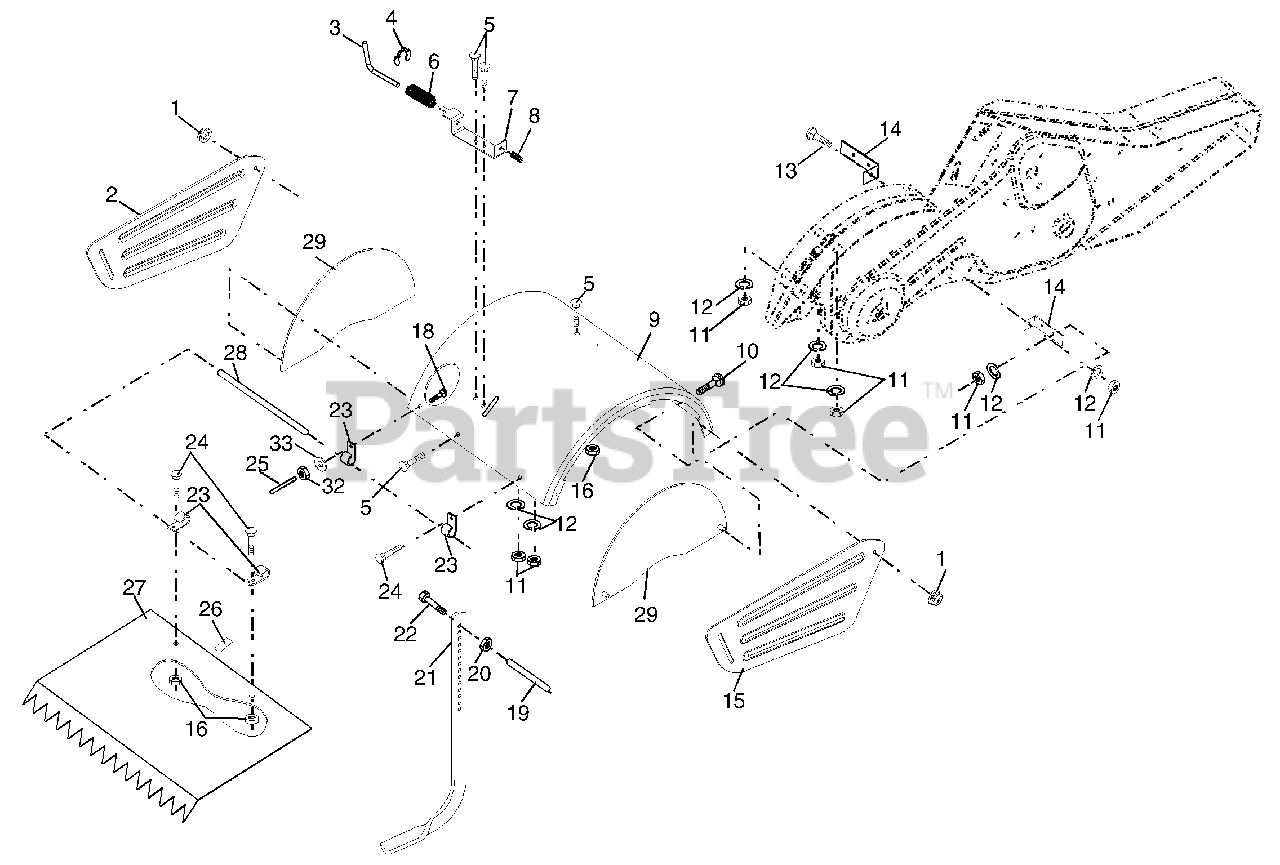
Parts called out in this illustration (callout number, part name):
1	Nut, Lock Hex Flange 5/16-18
2	Shield, Side, Outer L. H.
3	Pin, Stake, Depth
4	Ring, Klip
5	Bolt, Rdhd Sqnk 5/16-18 x 3/4
7	Bracket, Latch
8	Spring, Depth Stake
9	Shield, Tine
10	Bolt, Carriage 5/16-18 unc x 1
11	Nut, Hex 5/16-18
12	Washer, Lock 5/16
13	Bolt, Carriage 5/16-18 x 1-1/4
14	Bracket, Shield Tine
15	Shield, Side, Outer R.H.
16	Nut, Hex Flange 1/4-20 unc
18	Bolt, Carriage 1/4-20 x 1-1/4 Gr. 5
20	Nut, Hex 3/8-16
21	Stake, Depth
22	Bolt, Hex 3/8-16 x 2
24	Bolt, Carriage 1/4-20 x 1/2 Gr. 5
25	Cap, Vinyl
26	Pad, Idler
27	Shield, Leveling
28	Pin, Hinge
29	Shield, Side
32	Nut Fin Hex 1/4-20 unc
33	Washer Lock Hvy Helical 1/4
